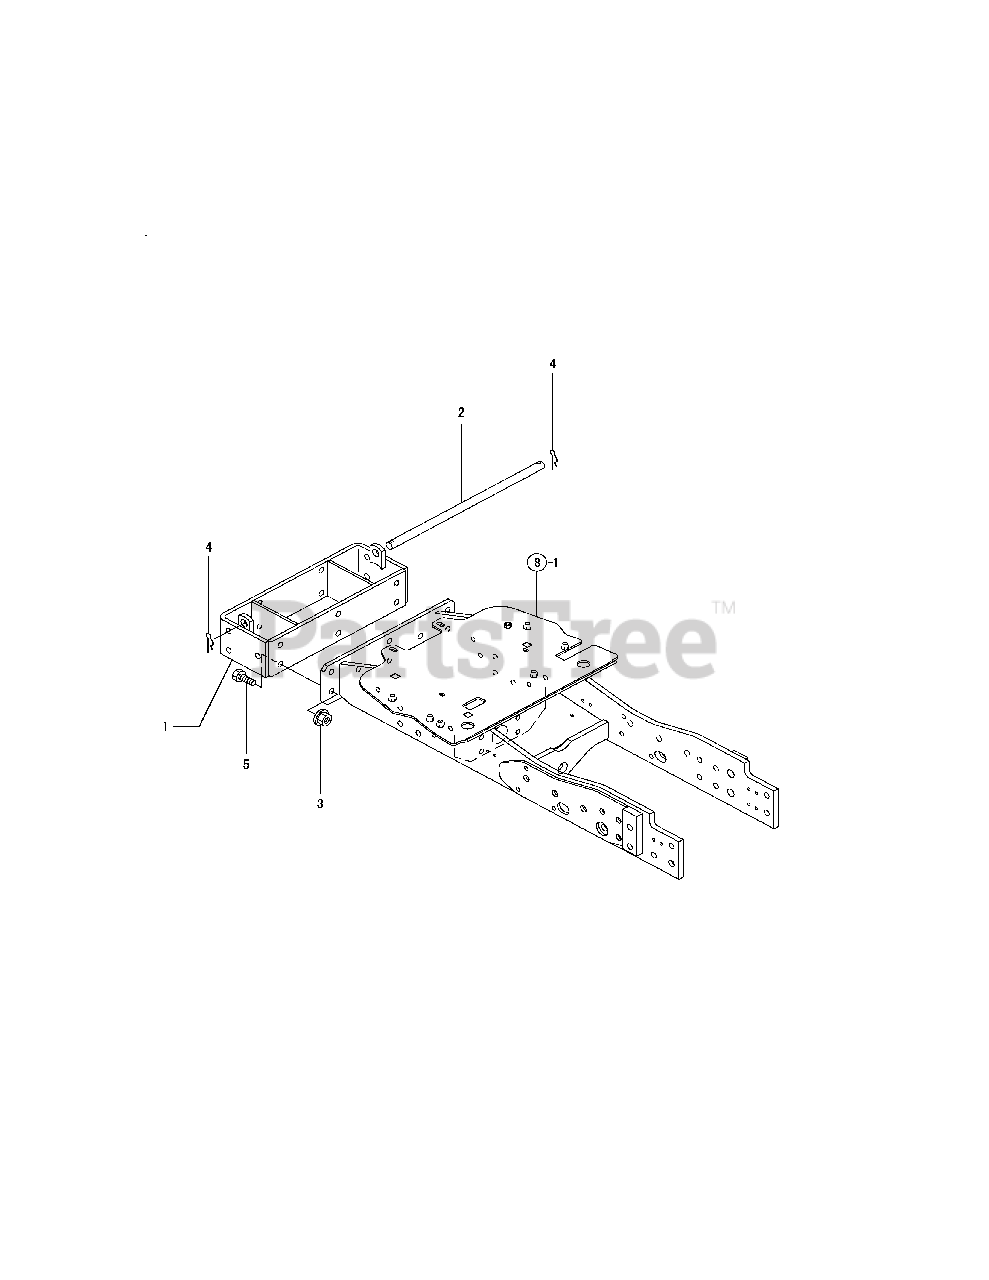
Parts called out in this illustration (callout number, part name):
1	BRACKET, FRONT
3	NUT W/WASHER 12
5	BOLT M12X 35 PLATED
